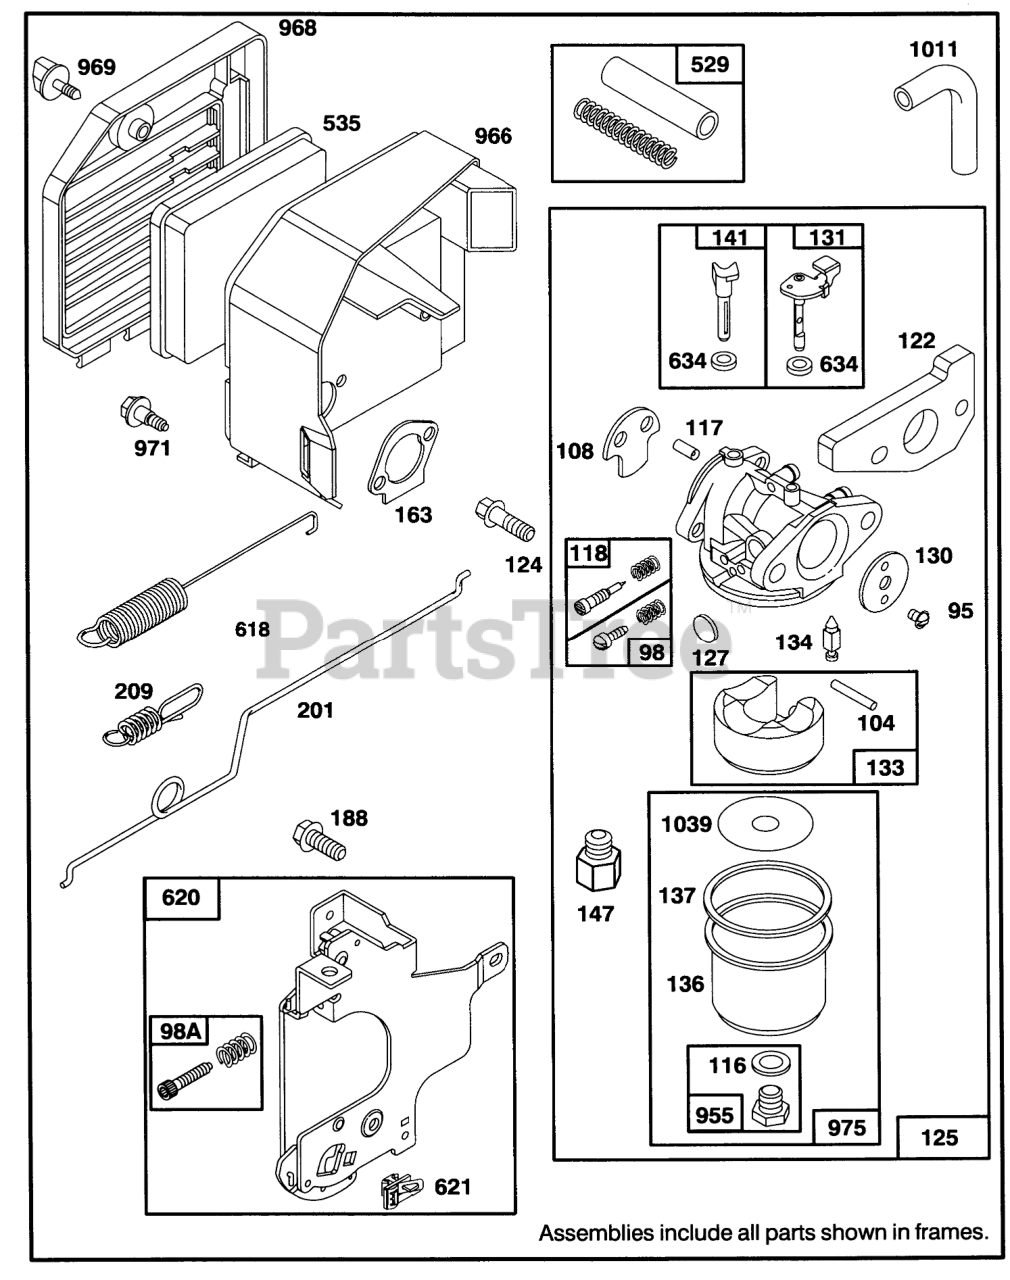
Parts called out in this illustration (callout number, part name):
95	SCREW - ROUND HEAD
98	IDLE ADJUSTING SCREW
98A	SPEED ADJUST. SCREW ASM
104	FLOAT HINGE PIN
108	CHOKE VALVE
116	SEALING GASKET
117	JET
118	VALVE KIT - NEEDLE
122	ADAPTER ASSEMBLY
124	HEX HEAD SCREW
125	CARBURETOR ASSEMBLY
127	PLUG
130	THROTTLE VALVE
131	THROTTLE SHAFT
133	FLOAT-CARBURETOR
134	Valve-Float (Includes Seat)
136	FLOAT BOWL
137	FLOAT BOWL GASKET
141	CHOKE SHAFT
147	JET ADAPTER
163	AIR CLEANER GASKET
188	SCREW - SEM
201	GOVERNOR LINK
209	GOVERNOR SPRING
529	BREATHER TUBE
535	FILTER ELEMENT
618	RETURN SPRING
620	CARBURETOR BRACKET
621	STOP SWITCH
634	SEAL WASHER
955	HEX HEAD SCREW
966	AIR CLEANER BASE
968	AIR CLEANER COVER
969	AIR CLEANER SCREW
971	AIR CLEANER SCREW
975	CARBURETOR BOWL ASM
1011	VENT TUBE
1039	FLOAT LIMITER
